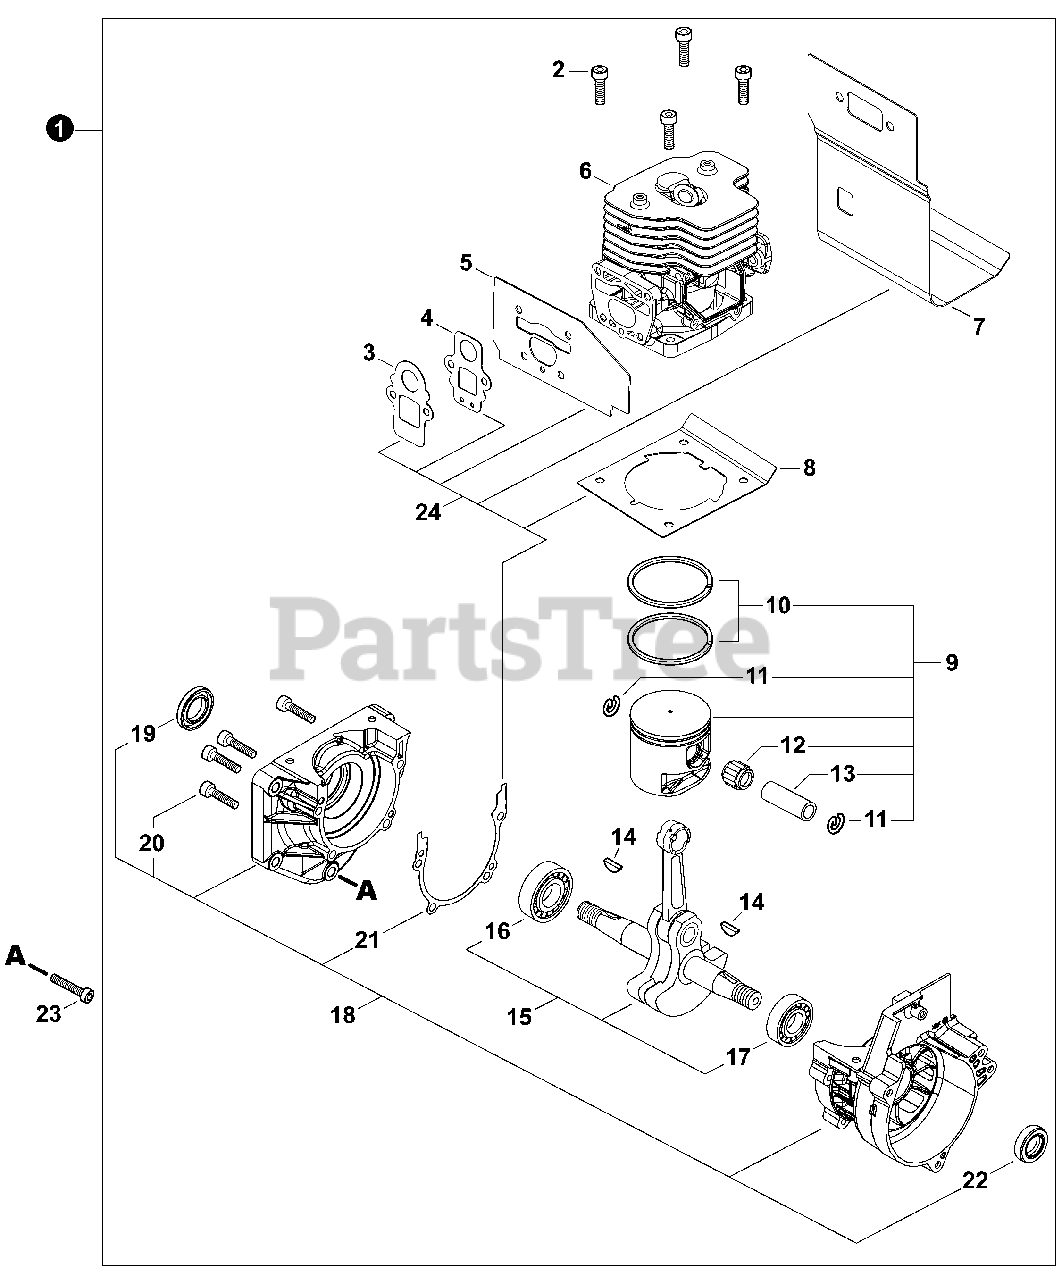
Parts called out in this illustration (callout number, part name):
1	SHORT BLOCK
2	BOLT, TORX 5x25
3	GASKET, INTAKE
4	GASKET, INTAKE
5	HEAT SHIELD, INTAKE
6	CYLINDER ASSY
7	GASKET, EXHAUST
8	HEAT SHIELD, EXHAUST
9	GASKET, CYLINDER
10	PISTON KIT
11	RING, PISTON
12	RING, RETAINING
13	BEARING, NEEDLE 13
14	PIN, PISTON
15	KEY, WOODRUFF 3x14
16	CRANKSHAFT ASSY
17	BEARING, BALL 6203
18	BEARING, BALL 6202
19	CRANKCASE SET
20	SEAL, OIL 17
21	BOLT, TORX 5x35
22	GASKET, CRANKCASE
23	SEAL, OIL 15
24	BOLT 6x30
25	GASKET KIT: ENGINE, INTAKE, EXHAUST
